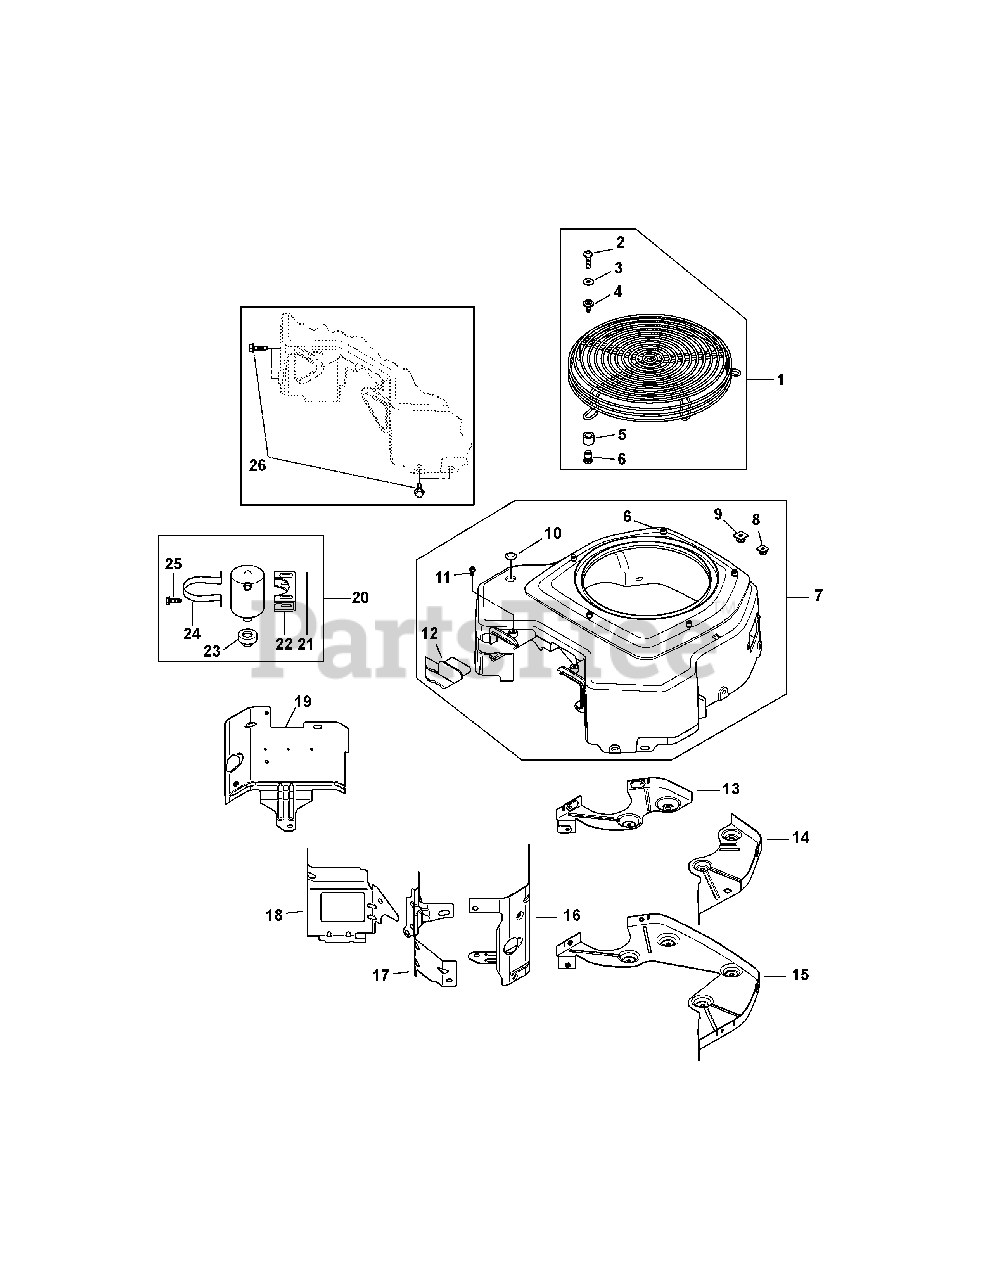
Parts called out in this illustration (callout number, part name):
1	KIT, GUARD
2	SCREW, LBD SKT PAN M5X0.8X15
3	WASHER, FLAT 7/32''
4	SCREW, SEMS
5	INSERT, THREADED
6	SPACER
7	KIT, BLOWER HOUSING ASSEMBLY
9	PLASTIC NUT
9	NUT, PLASTIC - BLACK
10	PLUG, BUTTON 9/16
11	SCREW, WSH HD TAP #8-18X1/2''
12	COVER, BLOWER HOUSING-MOLDED
13	PLATE, BACKING #1 SIDE
14	PLATE, BACKING #2 SIDE
14	KIT, BACKING PLATE
15	BACKING PLATE
16	KIT, CYL BAFFEL #2 SIDE
17	BAFFLE, VALLEY #2 CYLINDER
18	BAFFLE, VALLEY #1 CYLINDER
19	KIT, CYL BAFFEL #1 SIDE
20	KIT, BREATHER SEPARATOR
22	BRACKET, BREATHER SEPARATOR
23	GROMMET, RUBBER
24	STRAP, BREATHER
25	SCREW, FLG THD FRM M5X0.8X16
26	SCREW, FLG THD FRM M6X1.0X16
